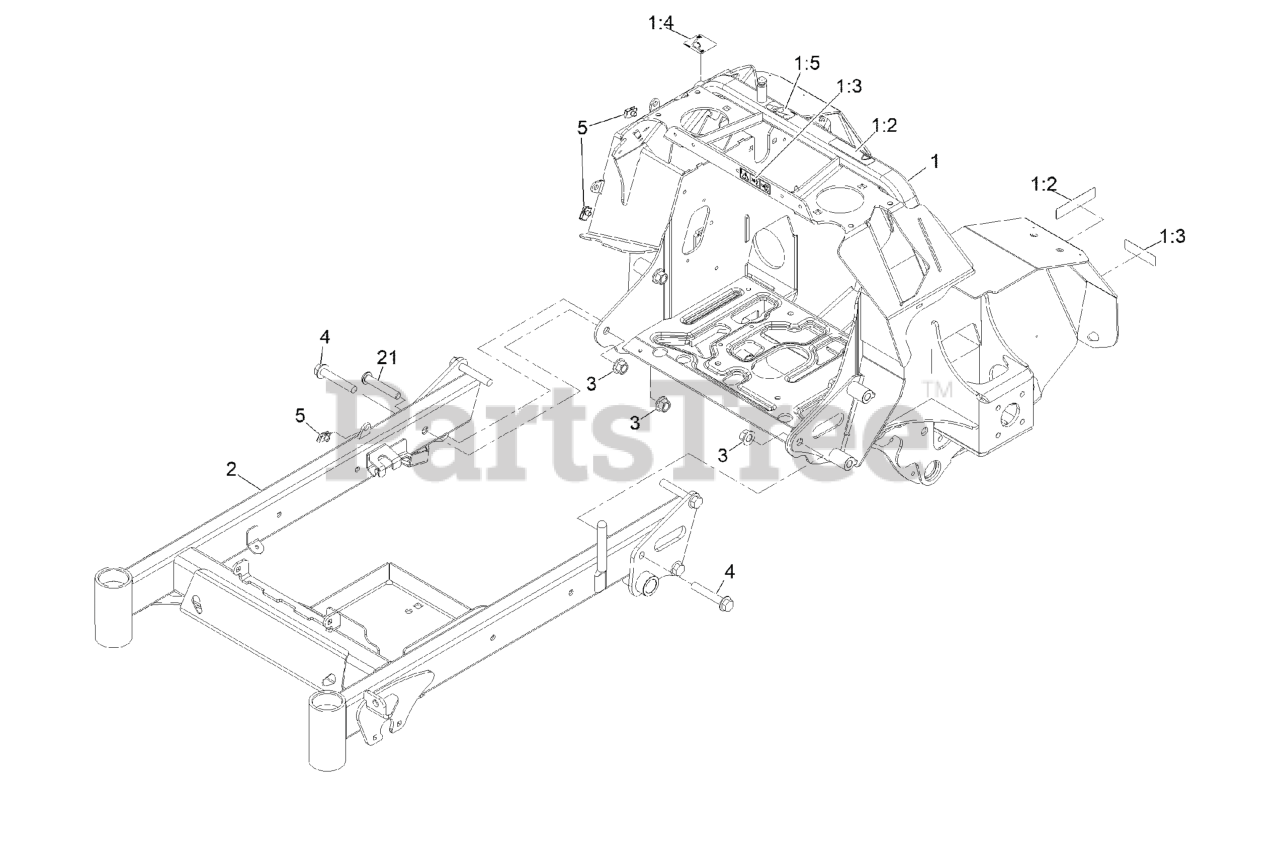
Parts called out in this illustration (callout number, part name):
1	ASM, REAR FRAME W/ DECALS
1:2	DECAL-WARNING
1:3	DECAL, COVER MISSING
1:4	DECAL-PARK BRAKE, CE
1:5	DECAL-BELT ROUTING HYD
2	WELD, FRONT FRAME, 36
3	Nut-Lock 1/2-13
4	SCREW-HF
21	SCREW, HSBH
